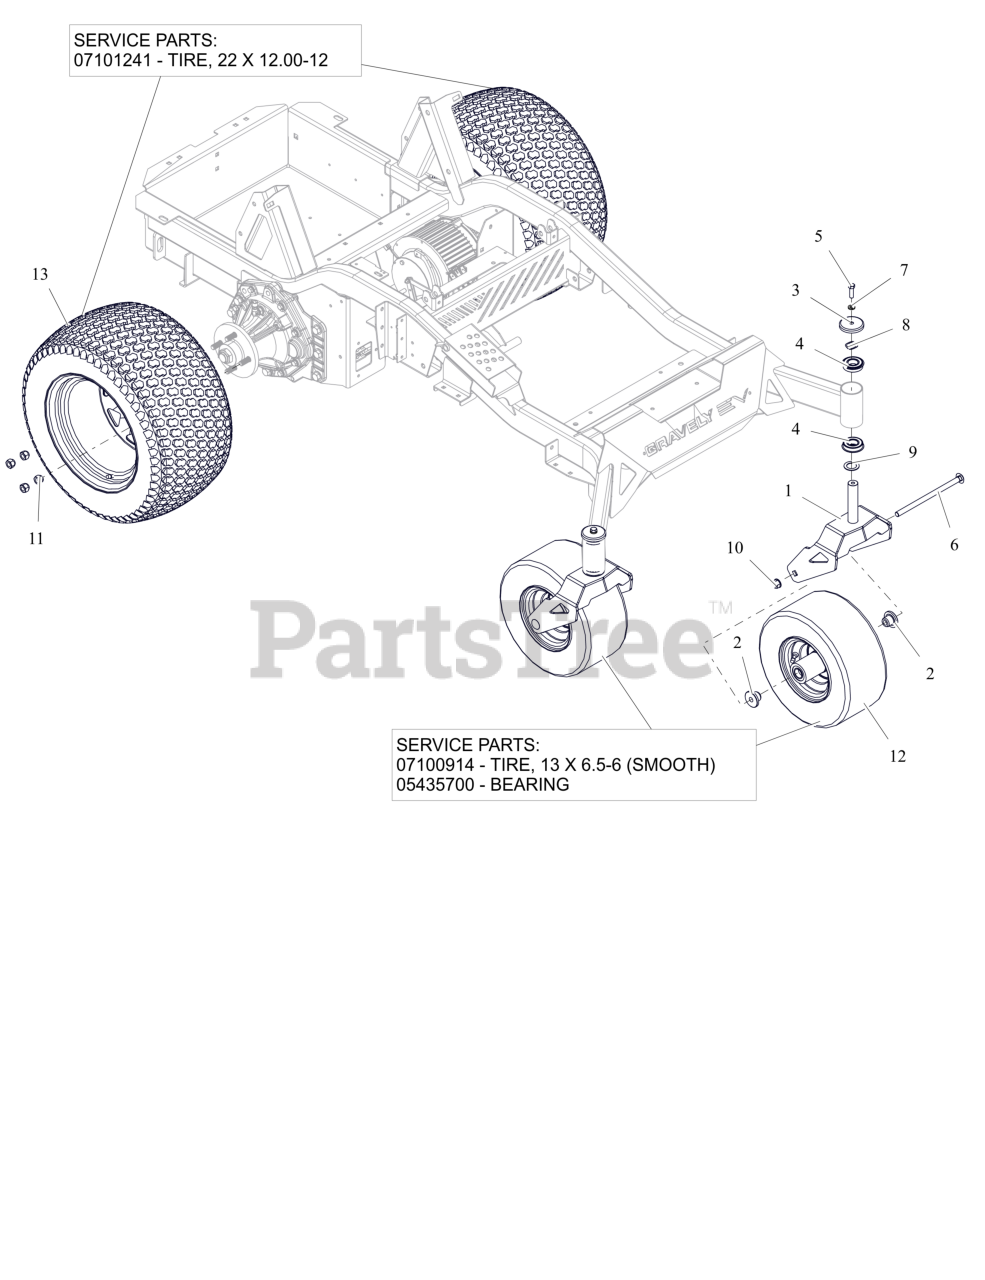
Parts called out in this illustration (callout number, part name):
1	WLDMT, CASTER FORK-HD (RED)
2	SPACER, FRONT WHEEL
3	SHIELD, AXLE BEARING
4	BEARING, BALL -2.000 OD X 1.000 ID X .5625 W/RING
5	BLT, HEX .38-16X1.25 G5 ZCC
6	BTL,RHSN .500-13 X 9 G5 ZCC
7	WSHR, LK-HVY .375X.115 ZCC
8	WSHR-WAVE 1.0X1.25X.028 .145FH
9	WSHR-HRD-THRS 1.007X1.542X.062
10	NUT-LK-CTR-FLG .500-13 GG ZCC
11	NUT, WHEEL .50-20 ZCC
12	ASM, WHL/TIRE 13X6.50-6
12	TIRE, 13X6.50-6 SMOOTH
12	TIRE TUBE 13X6.5-6
12	BRG, 25MM ID X 52MM OD X 15MM
13	ASM, WHL/TIRE 22X12.00-12 K500
13	TIRE, 22X12.00-12
13	TUBE 22,23&24X8.50/9.50/10.00/10.50/12.00-12
